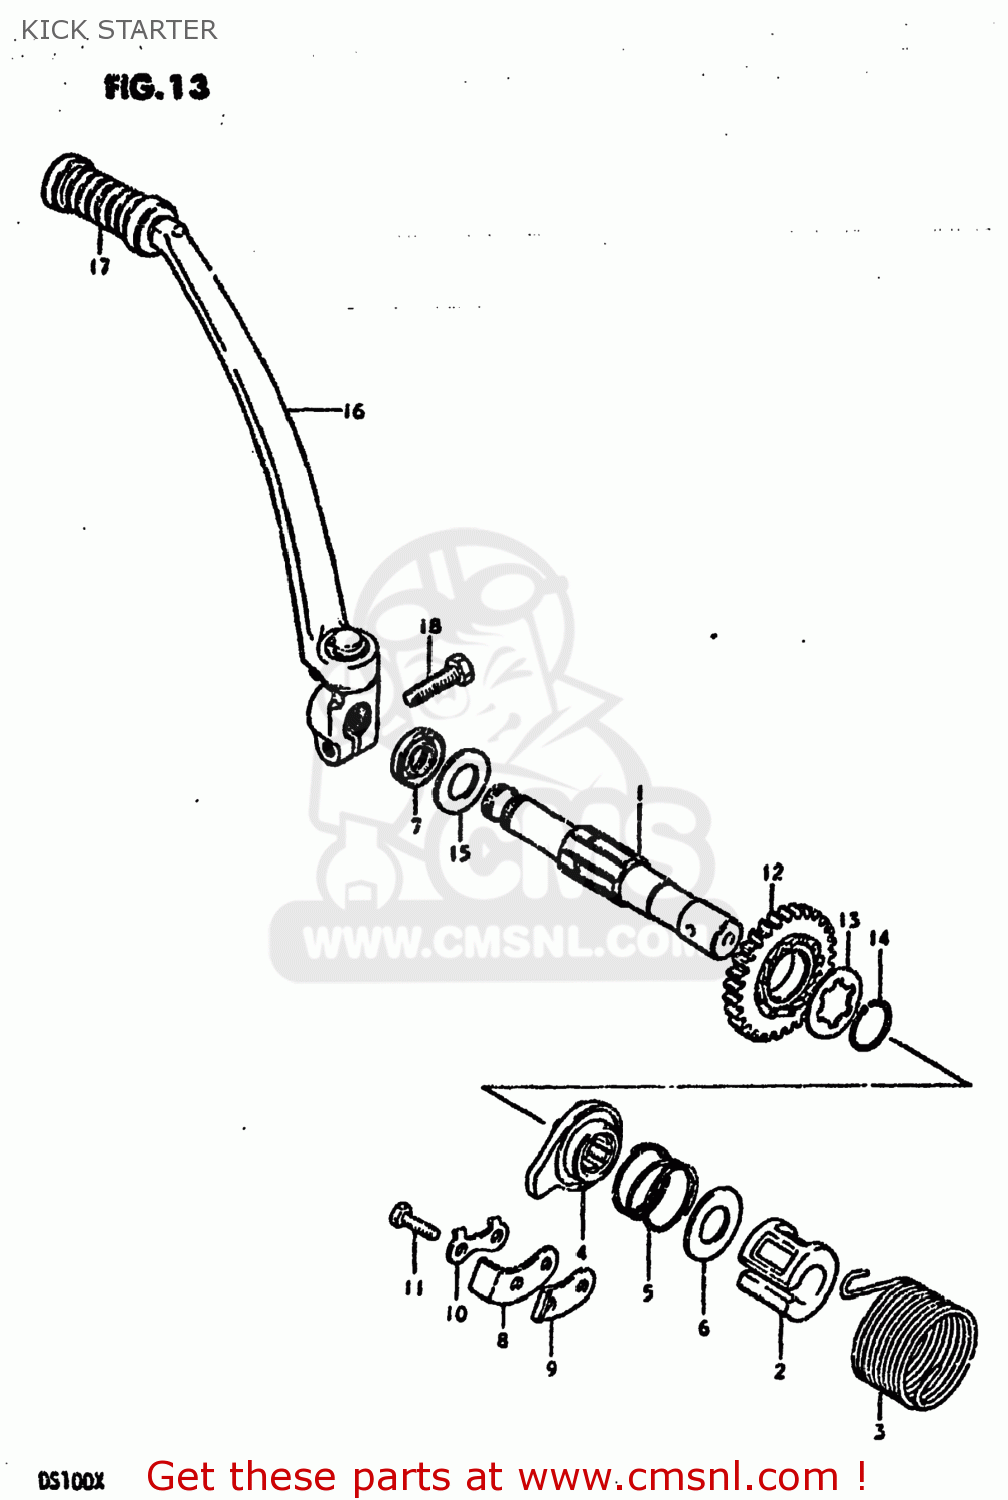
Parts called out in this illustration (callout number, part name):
1	SHAFT,KICK STARTER
2	GUIDE,KICK STARTER SFT SPRING
3	SPRING
4	STARTER,KICK
5	SPRING
6	WASHER
7	SEAL,OIL(16X30X8)
8	GUIDE,KICK STARTER
9	STOPPER,KICK STARTER
10	WASHER
11	BOLT, UPPER
12	GEAR,KICK STARTER DRIVE
13	WASHER,LOCK
14	CIRCLIP
15	WASHER(16X30X1)
16	LEVER ASSEMBLY,KICK STARTER
17	RUBBER,KICK STARTER PEDAL
18	BOLT
